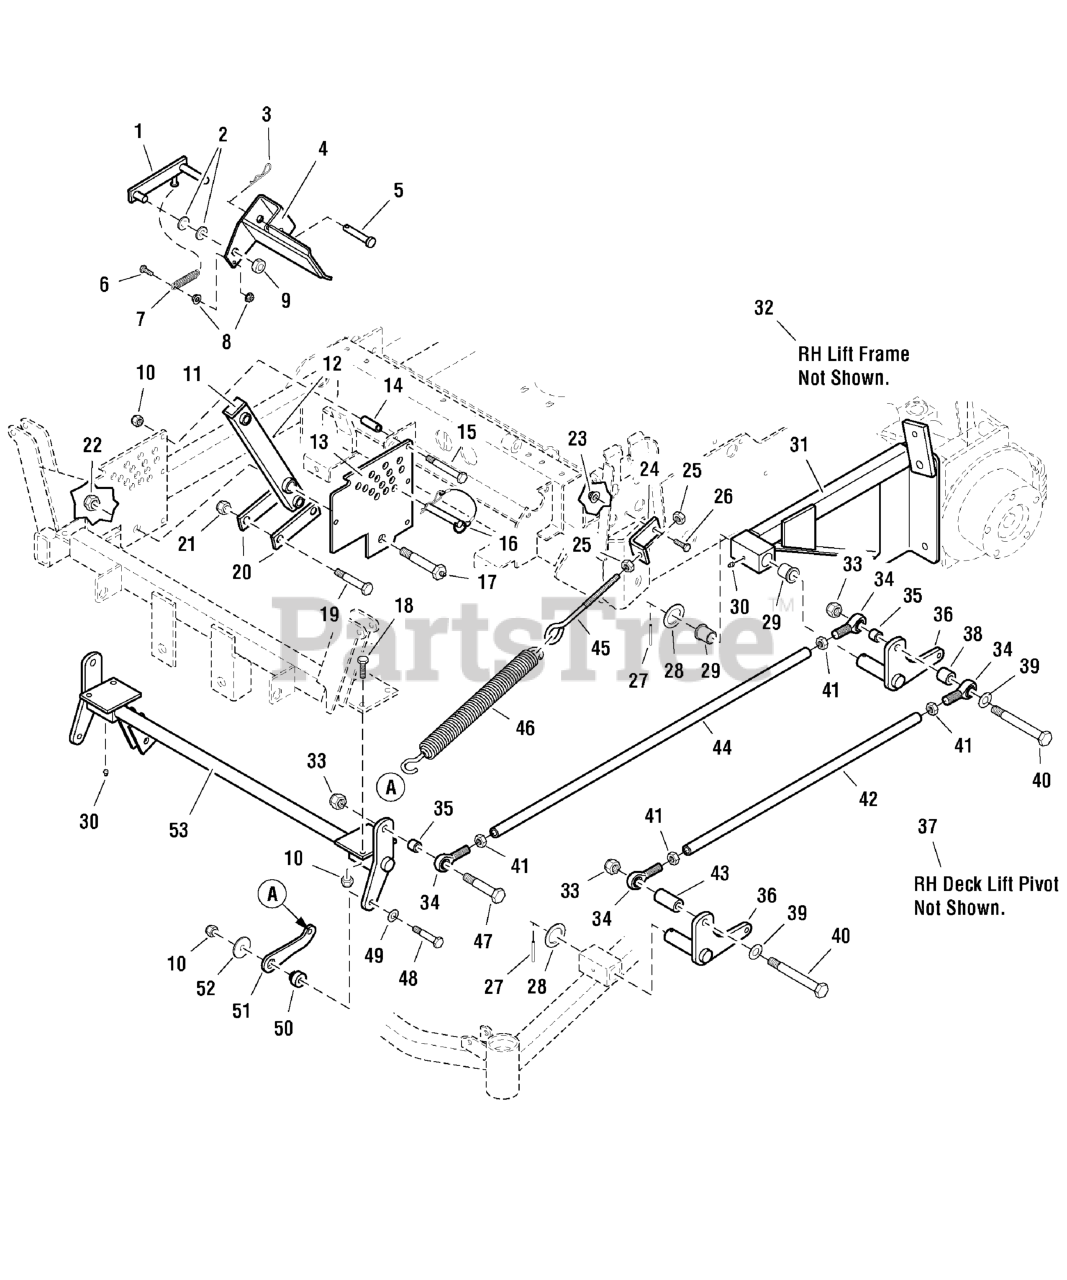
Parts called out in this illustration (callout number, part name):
1	DECK LIFT LOCK
2	WASHER, 1/2 SAE
3	HAIRPIN CLIP
4	WELD, DECK LIFT PEDAL
5	PIN, Clevis, 1/2 x 2-1/2
6	BOLT, 1/4-20 x 3/4
7	SPRING, Extension
8	NUT, 1/4-20 HEX SERR. FLANGE
9	COLLAR, Split, 1/2
10	NUT, 3/8-16 HEX NYLON LOCK
12	ARM, Deck Lift Pivot
13	DECK HEIGHT PLATE
14	SPACER, .38 x .50 x 1.56
15	BOLT, 3/8-16 X 2-3/4" GD5 CZ
16	PIN, 1/2 x 3-1/2 w/ Lanyard
17	LIFT PIVOT BOLT
18	BOLT, 3/8-16 X 1-1/4" GD5 CZ
19	BOLT, 1/2-20 x 3
20	DECK LIFT LINK
21	NUT, Hex, Nylon Lock, 1/2-20
22	NUT, 5/8-11 Hex Jam Nylon Lock
23	NUT, 5/16-18 Hex Nylock Flange
24	EYEBOLT ANCHOR
25	NUT, 3/8-16 Hex
26	BOLT, 5/16-18 X 1 GD5 YZ
27	PIN, Roll, 3/16 x 1-1/2
29	BUSHING, Flange
30	GREASE FITTING
31	LIFT FRAME ASSEMBLY - LH, Complete
33	NUT, 1/2-13 HEX NYLON LOCK
34	BALL JOINT, 1/2-20 Male
35	SPACER, .51 X .75 X .56
36	DECK LIFT PIVOT - LH
38	SPACER, .52 x 1.00 x 1.00
39	WASHER, 1/2 SAE
40	BOLT, 1/2-13 X 4" GD5 CZ
41	NUT, 1/2-20 Hex
42	DECK LIFT ROD - OUTER
43	SPACER, .50 x 1.00 x 2.00
44	DECK LIFT ROD - INNER
45	EYEBOLT, 3/8" x 8"
46	DECK LIFT SPRING
47	BOLT, 1/2-13 x 2-1/4
48	BOLT, 3/8-16 X 2, GD5, CZ
49	WASHER, 3/8 SAE
50	DECK PIVOT BUSHING
51	SPRING LINK
52	WASHER, 3/8 x 2
53	DECK LIFT SHAFT & MOUNT ASSEMBLY
